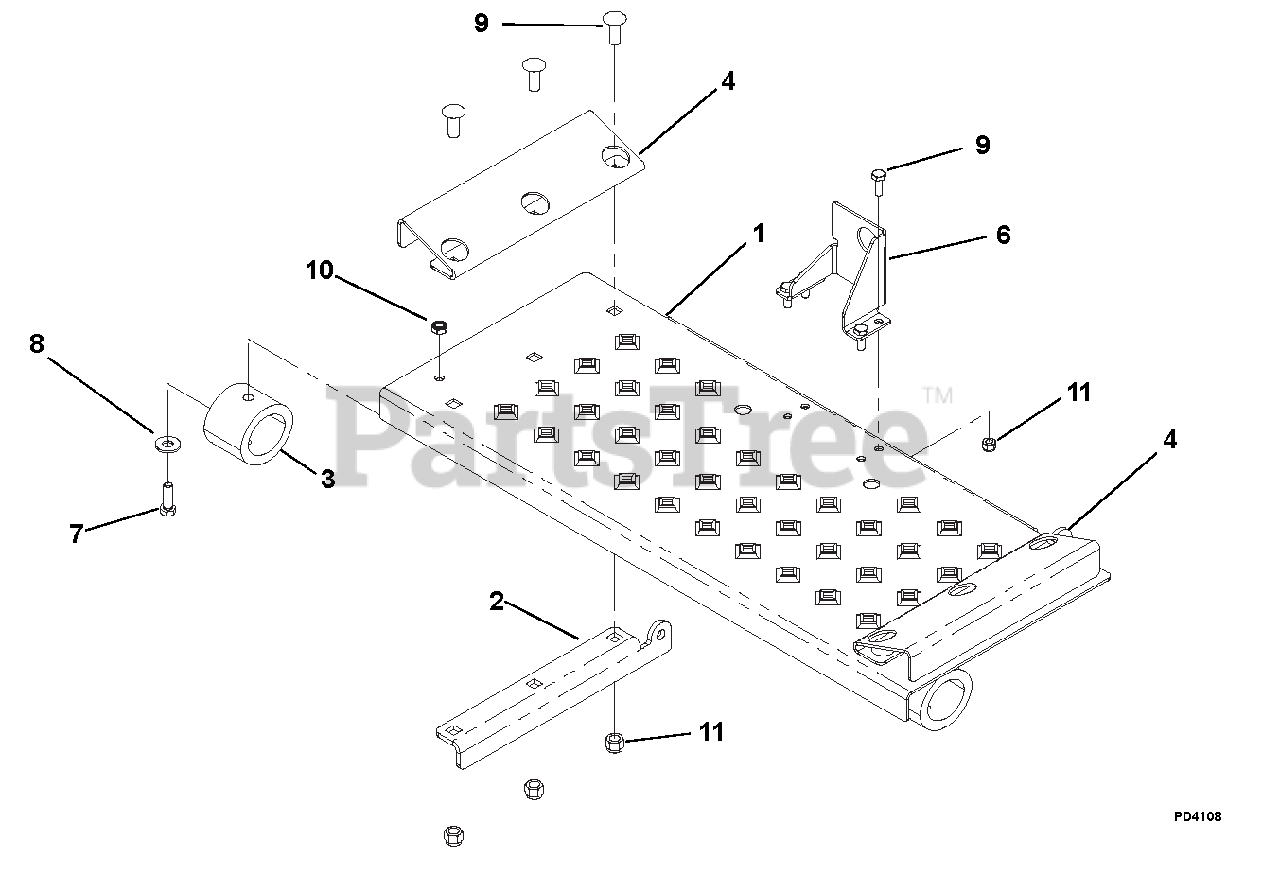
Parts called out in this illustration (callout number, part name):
1	PLATE, PLATFORM
2	PLATE, PLATFORM TAB
3	CLUTCH ASSY, OGURA
4	WEDGE, PLATFORM
5	PLATE, PLATFORM TAB LH
6	COVER, OPC
7	@BLT-HEX .31-18X1.00 GR5 YWZC
8	@WSHR-FL-STL.38X.875X.083 YWZC
9	@BLT-RDHDSHSQNK.38-16X1.0 G5YZ
10	@NUT-LK-NYL .312-18 YWZC
11	@NUT-LK-NYL .38-16 YWZC
